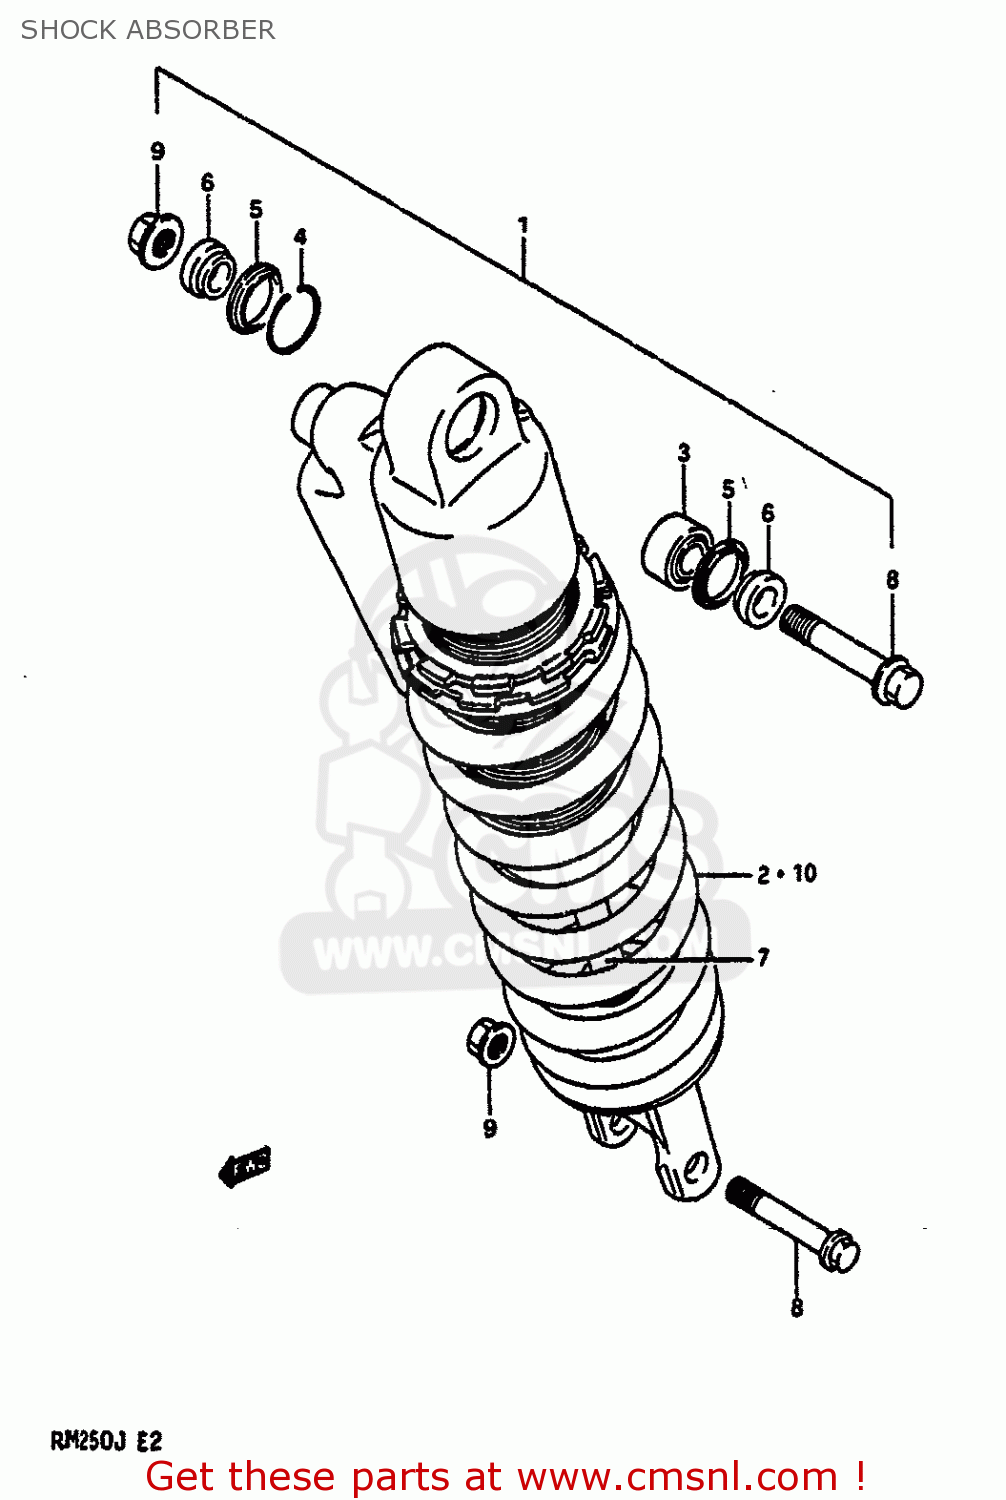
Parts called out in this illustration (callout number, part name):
1	ABSORBER ASSEMBLY,REAR SHOCK
2	SPRING
3	BEARING,RR CUSHION LEVER
4	RING
5	DUST SEAL
6	SPACER
7	ROD,PISTON
8	BOLT,REAR SHOCK ABSORBER
9	NUT
10	SPRING
